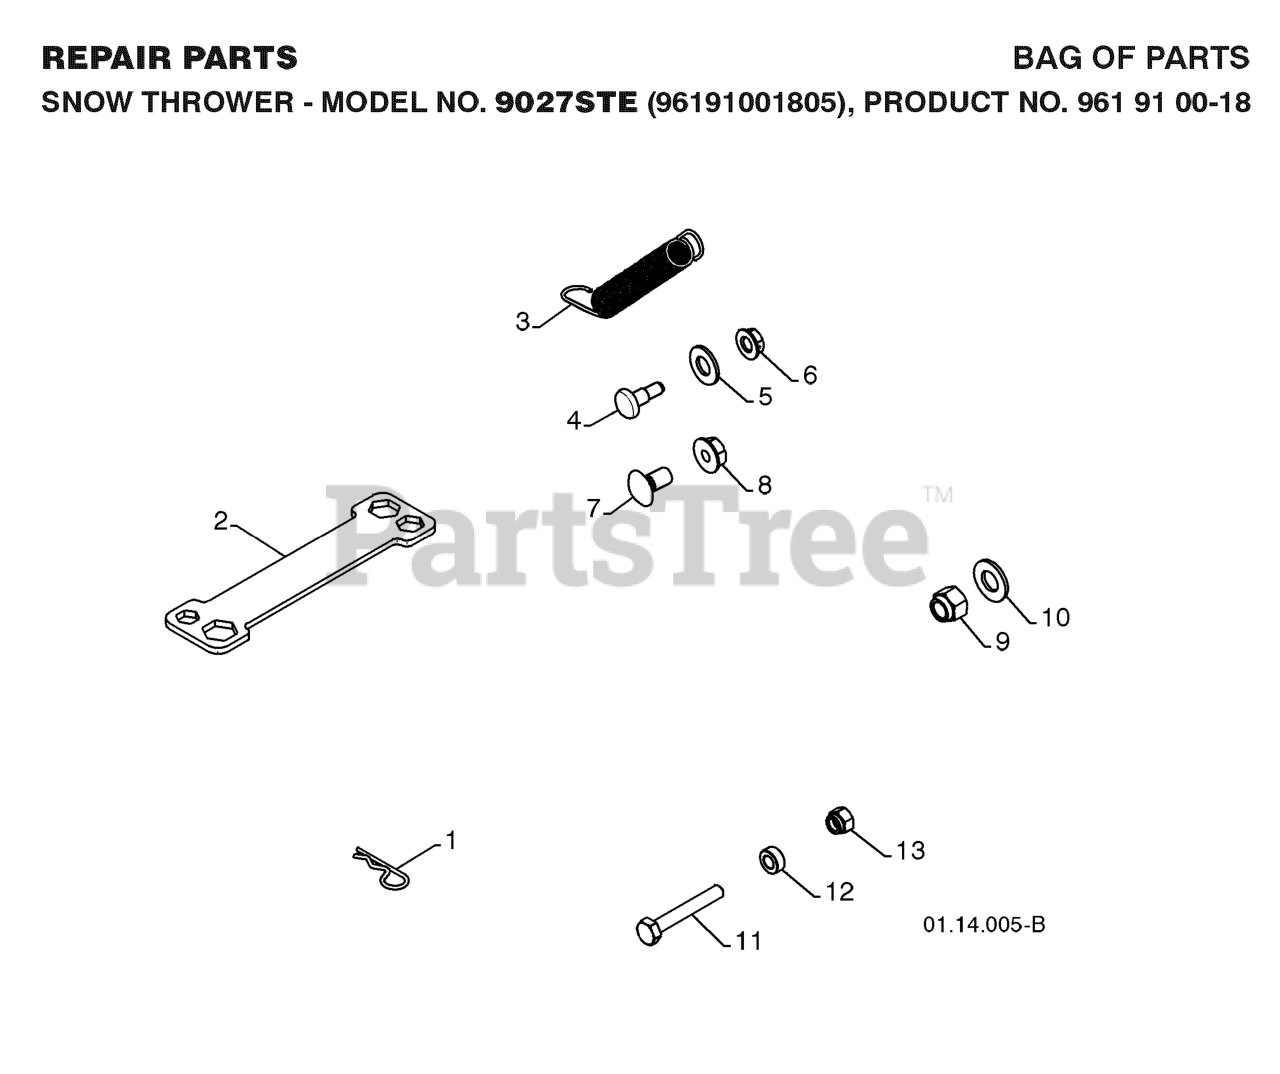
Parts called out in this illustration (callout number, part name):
1	SPRING RETAINER
2	RP WRENCH, SNOWTHROWER
3	SPRING.DEFLECTOR.REM.CHUTE
4	BOLT, SHOULDER
5	WASHER, NYLON FRICTION
6	NUT.HEX.FLANGE.1/4
7	BOLT
8	NUT.LOCK.5/16-18
9	NUT
10	WASHER
11	BOLT, SHEAR
12	SPACER.3943.SLEEVE.250X.47
13	LOCKNUT.NYLOC.1/4-20
